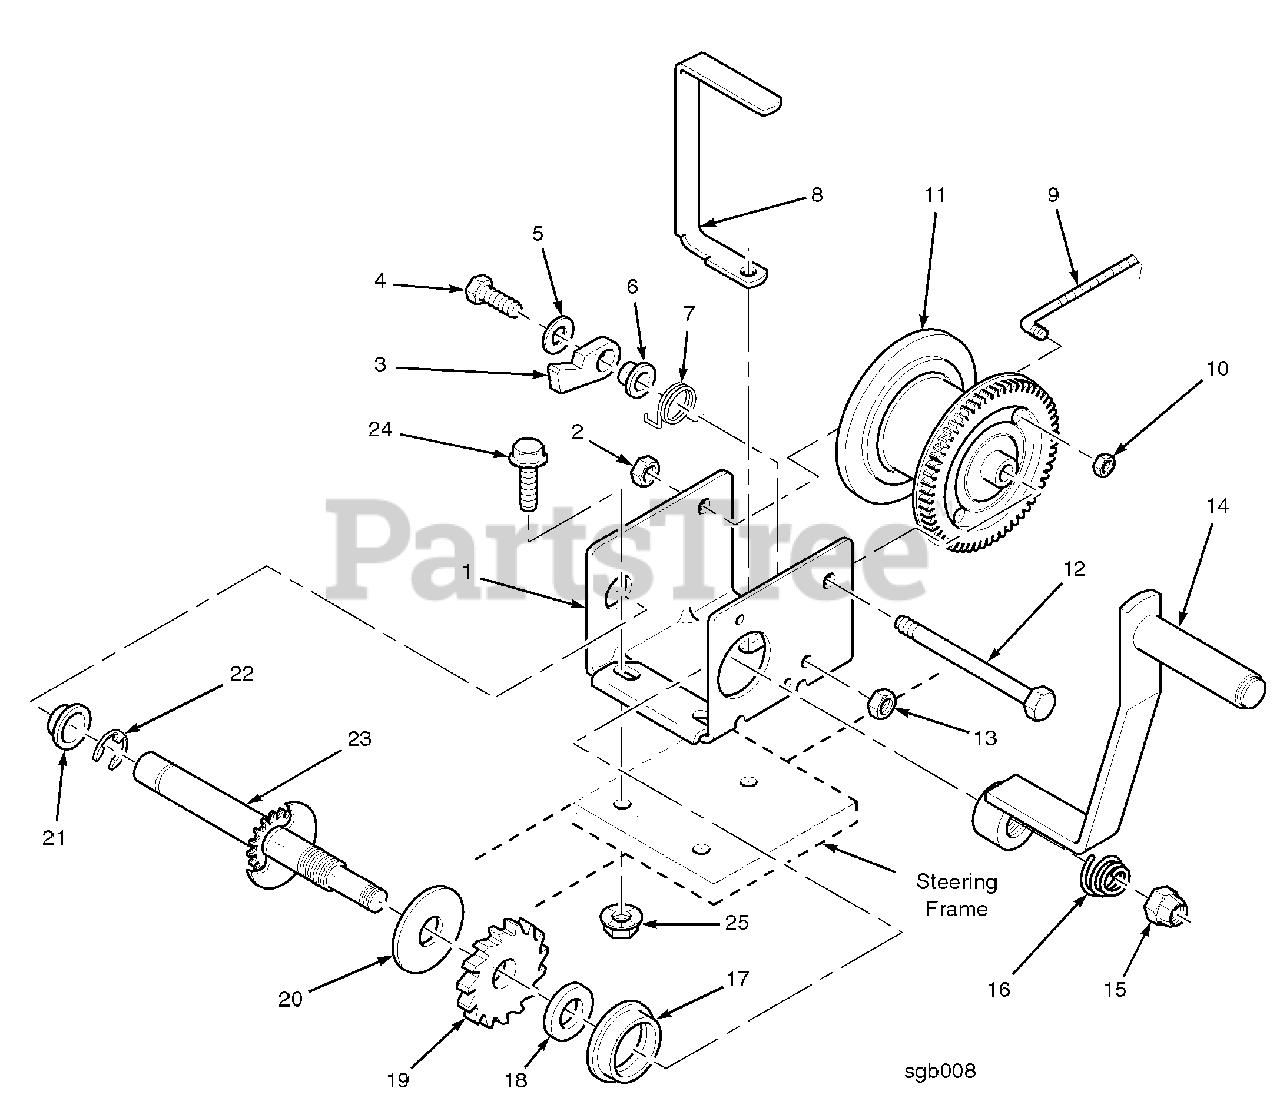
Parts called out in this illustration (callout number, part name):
1	Winch Assembly
2	Locknut, 7/16-14
3	Ratchet Pawl
4	Ratchet Bolt
5	Flatwasher
6	Ratchet Spacer
7	Ratchet Spring
8	Cable Guide
9	Winch Cable Assembly
10	Hex Locknut, 1/4-28
11	Winch Reel
12	Reel Shaft
13	Hex Locknut, 3/8-16
14	Winch Handle
15	Handle Nut
16	Handle Spring
17	Shaft Bushing
18	Pressure Washer
19	Ratchet Wheel
20	Pressure Plate
21	Shaft Bushing
22	E-Ring
23	Drive Shaft
24	Serr. Flg. HH Capscrew, 3/8-16 x 1"
25	Serr. Flg. HH Nut, 3/8-16
